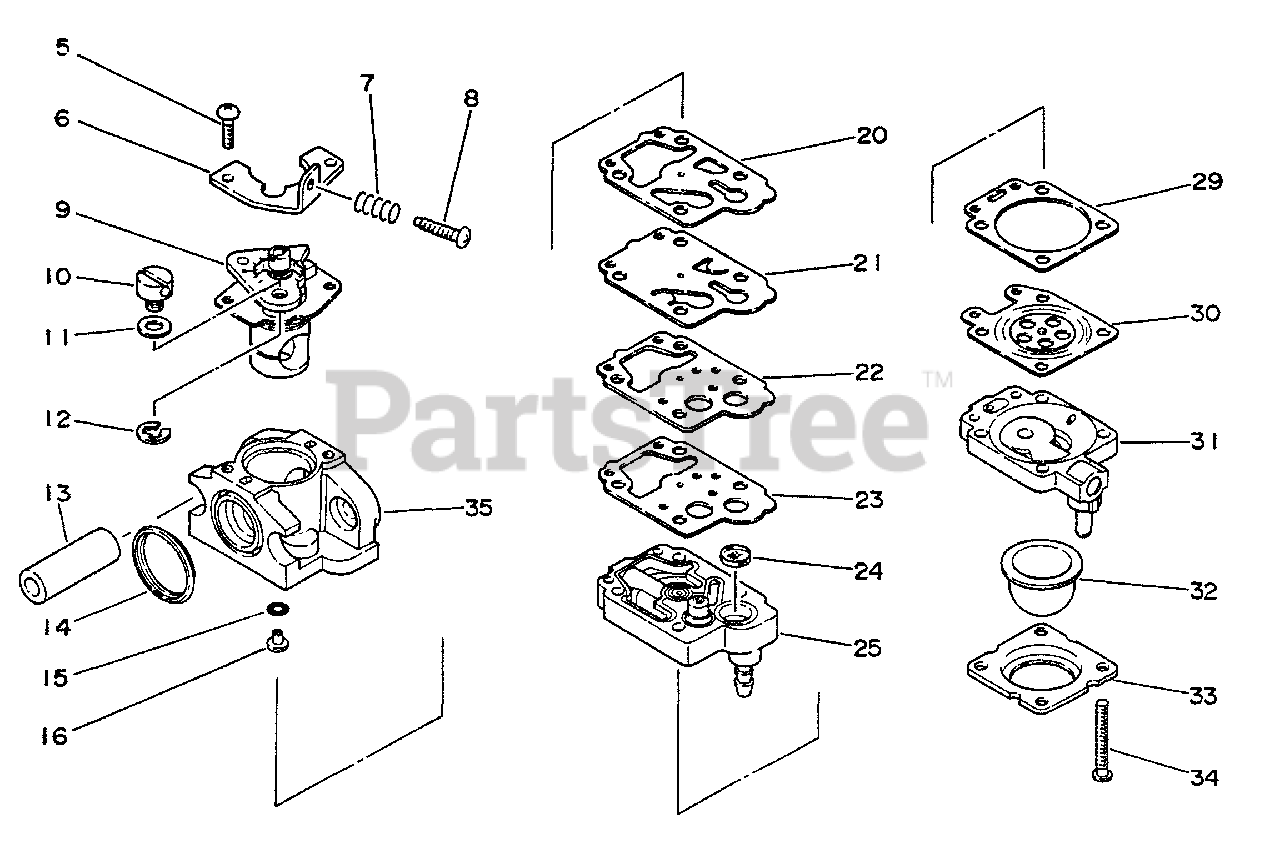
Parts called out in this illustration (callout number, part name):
6	BRACKET, THROTTLE CABLE
7	SPRING, IDLE ADJUST
8	SCREW, IDLE ADJUST
9	VALVE, THROTTLE
12	RING, RETAINING
13	SLEEVE, MOUNTING
14	SEAL
15	O-RING
16	JET
20	GASKET, PURGE
21	DIAPHRAGM, PURGE
22	PLATE, PUMP
23	GASKET, PLATE
24	STRAINER
25	BASE, PURGE
29	GASKET, METERING
30	DIAPHRAGM, METERING
31	BASE, PURGE
32	BULB, PURGE
33	RETAINER, PURGE BULB
35	BODY, CARBURETOR
